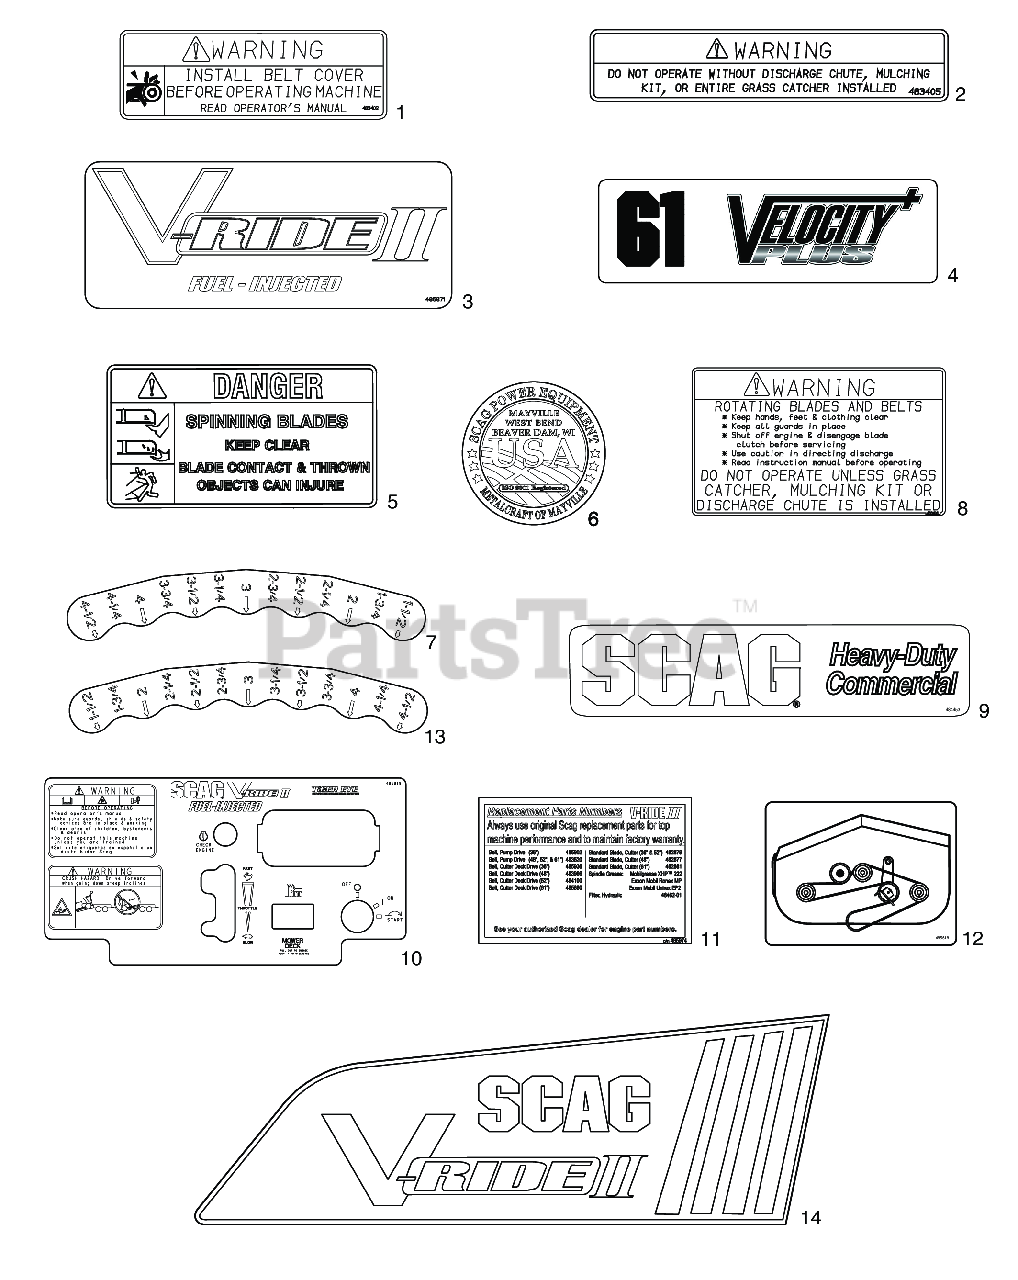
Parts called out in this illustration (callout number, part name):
1	Decal, Warning - Belt Cover
2	Decal, Warning-Discharge
3	Decal, Belt Cover
3	Decal, Belt Cover - EFI
4	Decal, 36 Advantage 483060
4	DECAL, VELOCITY PLUS - 48
4	Decal 52V 483201 Decal 61V
4	DECAL, VELOCITY PLUS - 61
5	Decal, Danger-Spinning Blades
6	Decal, Metalcraft - USA
7	Decal, Deck Height - Outer
8	Decal, Warning - Rotating Blades
9	Decal, Scag Heavy Duty Commercial
10	Decal, Instrument Panel - SVRII36A
10	Decal, Instrument Panel - SVRII36A - Recoil Start
10	Decal, Instrument Panel - SVRII
10	Decal, Instrument Panel - SVRII-EFI
11	Decal, SVRII Replacement Parts
12	Decal, Belt Routing - SVRII36A
12	Decal, Belt Routing - SVRII48V, SVRII52V & SVRII61V
13	Decal, Deck Height - Inner
14	Decal, Scag V-Ride II (Fuel Tank)
